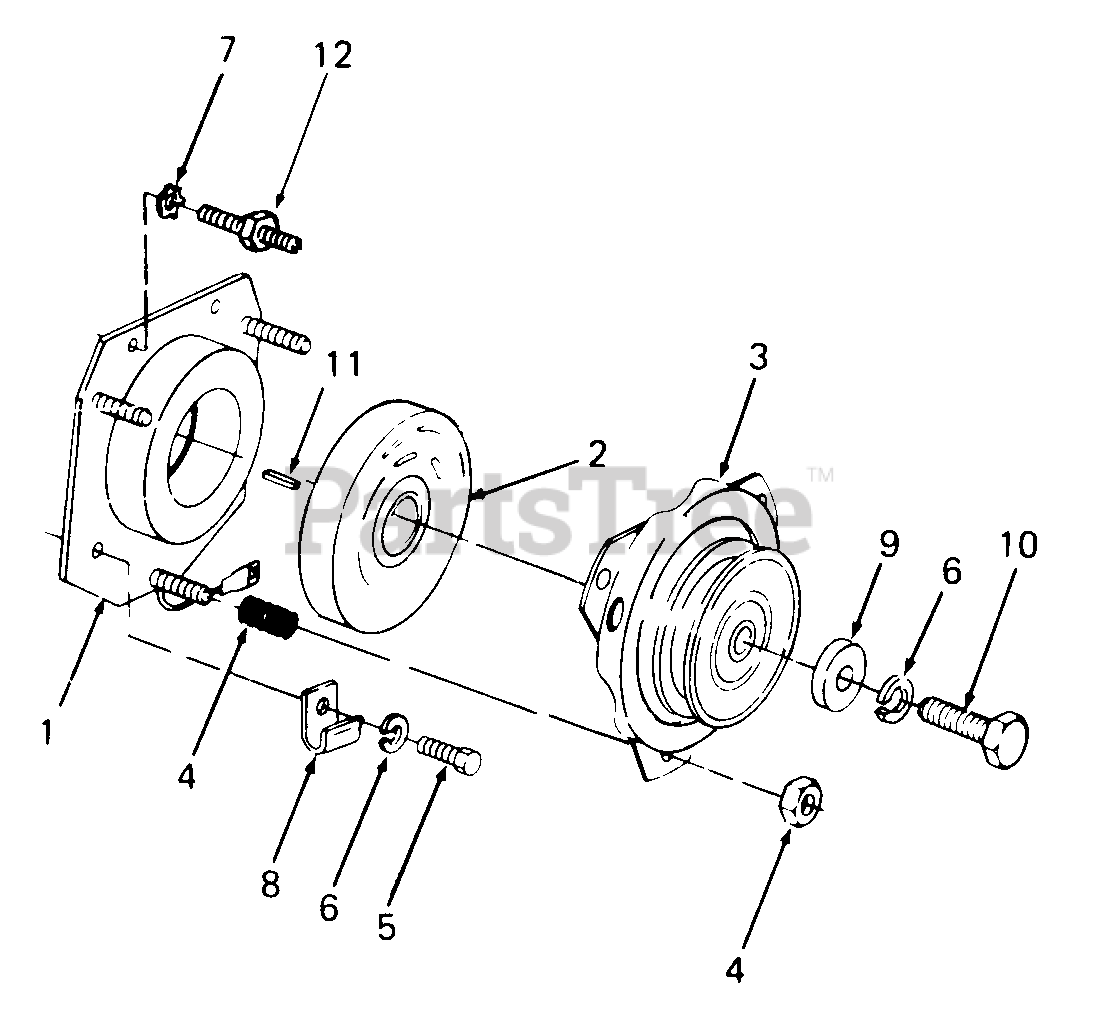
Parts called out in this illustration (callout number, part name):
4	Spring & Nut Kit
5	Screw, Hex Cap, 7/16-14 X .75 Lg GR5
6	Washer, Lock, 7/16
7	Washer, Ext Lock, .45 X .75. X .035 Thk
8	Clamp, Cable
9	Washer, Flat, .47 X 1.5 X .225 Thk
10	Screw, Hex Cap, 7/16-20 X 1.50 Lg GR5
11	Key, Square, 1/4 X .75 Lg
12	Stud, 7/16-14 Trd
